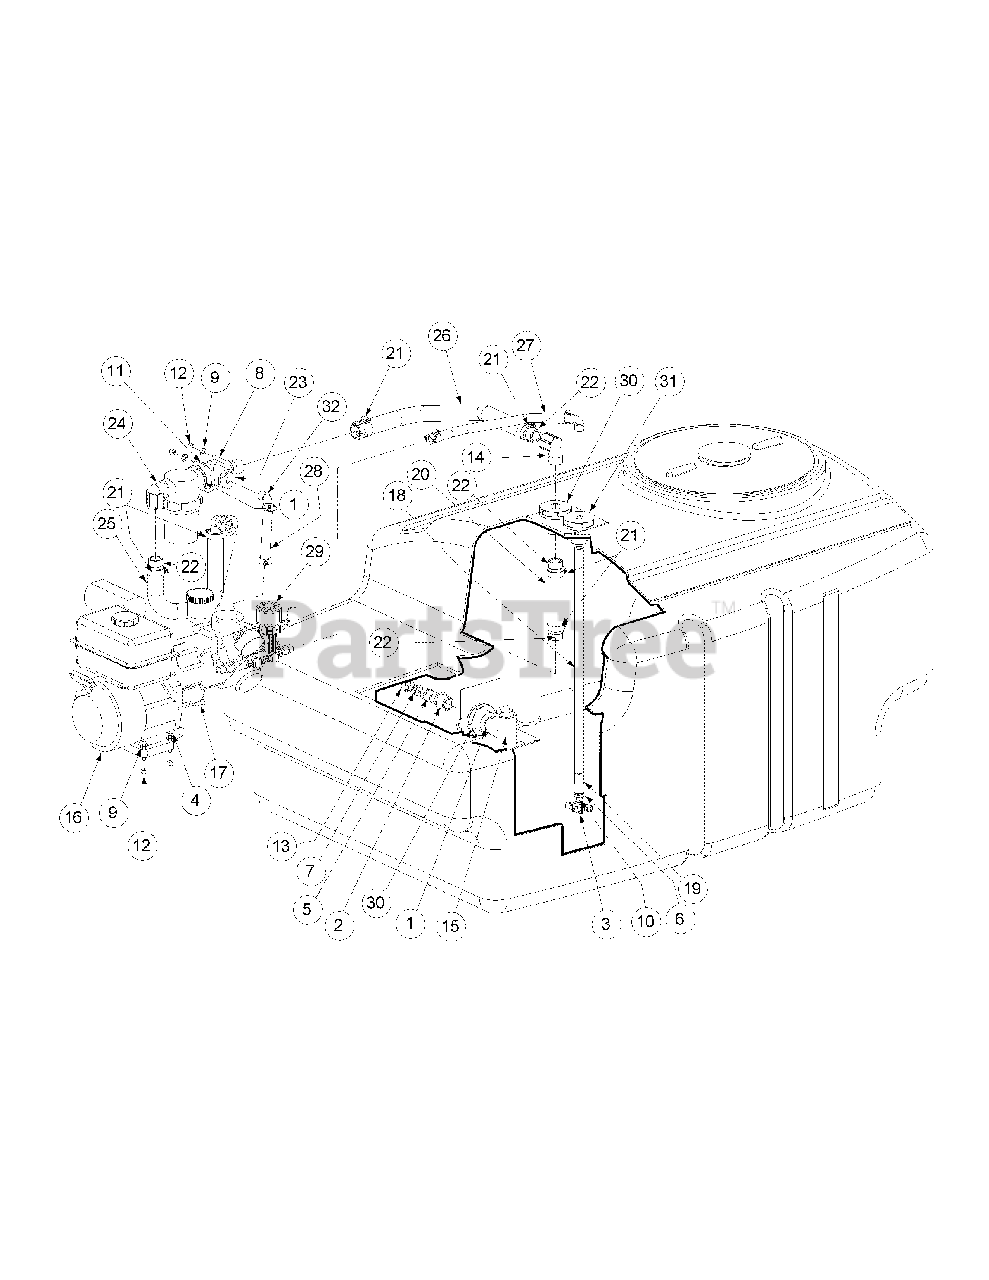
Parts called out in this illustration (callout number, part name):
1	NPT Close Nipple, 1"
2	NPT, 3/4" NPT, Adapter Bushing, 1"
3	Jet Agitator
4	Hex Cap Screw, 5/16-18, 1-3/4
5	3/4 NPT Fitting, 3/4 Hose Thread
6	1/4 FNPT, 1/2 MNPT Fitting
7	Rubber Washer, 3/4"
8	U-Bolt, 5/16-18 x 2
9	Flat Washer, 5/16
10	MNPT Close Nipple, 1/4
11	Rubber Pad, 1/4x 1-1/2 x 3
12	Nylock Nut, 5/16-18
13	Hose Cap 3/4
14	Street Elbow, 1" MNPT x 1" PVC
15	Tee 1" FNPT
16	5.5 HP Kawasaki Engine
17	Socket Head Capscrew, M8-1.25 x 25MM
18	Agitator Tube, 24" Extension PVC
19	Coupling, 1/2 FNPT
20	Inner Suction Hose Assembly
21	Hose Clamp, 7/8 x 1-1/4
22	Hose Barb, 1" NPT, 1" Nylon
23	NPT, 1/2" NPT, Adapter Bushing, 1"
24	Strainer Manifold Kit Includes:
24	Strainer, 30 Mesh-SS
24	Strainer Bowl
24	Strainer Gasket
24	Strainer Screen 30 Mesh
25	Strainer Suction Hose Assembly
26	Tank Suction Hose Assembly
27	Pump Agitator Hose Assembly
28	Bypass Pump Hose Assembly
29	Hydro Pump, D-403 includes:
29	Control Unit
29	Optional Hydro Pump Kits:
29	Hydro Pump Diaphragm Kit
29	Hydro Pump Valve Kit
29	Hydro Pump O-Ring Kit
29	Hydro Pump Pressure Regulator
30	1" Fitting
31	1/2" Fitting
32	Elbow Hose Barb, 1/2" NPT, 1" Nylon
